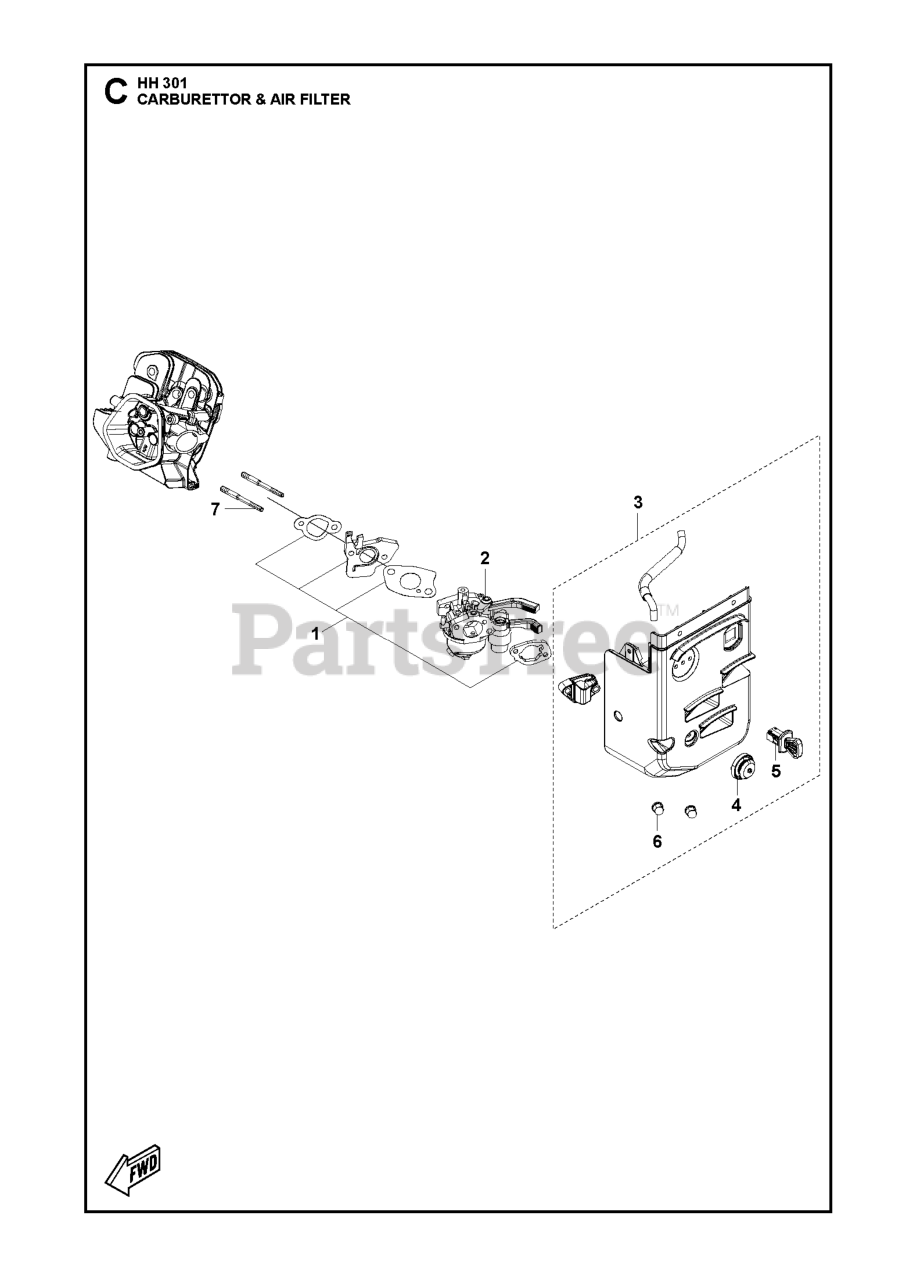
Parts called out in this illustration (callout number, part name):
1	GASKET KIT CARBURETTOR GASKET
2	CARBURETTOR
3	AIR FILTER ASSY
4	VALVE STARTING RICHED VALVE
5	SWITCH STOP ENGINE SWITCH
